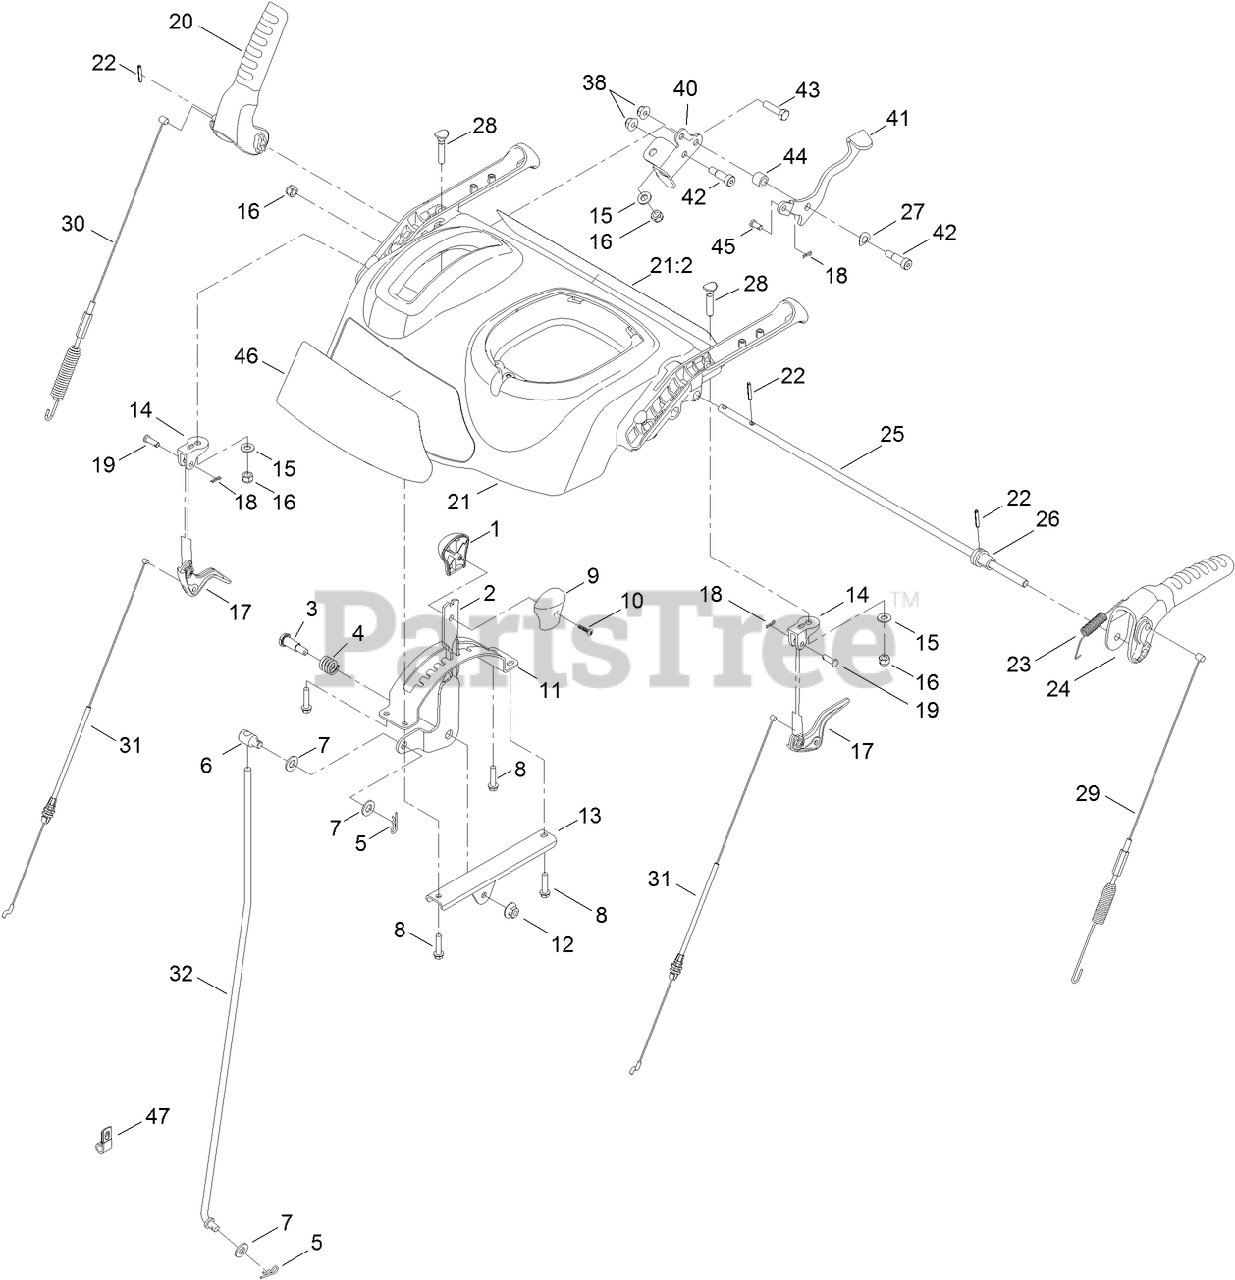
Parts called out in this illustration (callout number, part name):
1	KNOB-SHIFT, RH
2	SELECTOR-SPEED
3	SCREW-SHOULDER
4	SPRING-COMPRESSION
5	PIN-COTTER
6	TRUNNION-ROD
7	WASHER-FLAT
8	SCREW-PLASTITE
9	KNOB-SHIFT, LH
10	SCREW-PPH
11	GUIDE-SELECTOR, SPEED
12	NUT-HF
13	MOUNT-SELECTOR, SPEED
14	MOUNT-CLUTCH, LEVER
15	WASHER-FLAT
16	NUT-LOCK, NI
17	LEVER-CLUTCH
18	PIN-HAIR
19	PIN-CLEVIS
20	LEVER-AUGER
21	CONTROL PANEL ASM
21:2	DECAL-CONTROL, PANEL
22	PIN-SPRING
23	SPRING-TENSION
24	LEVER-TRACTION
25	ROD-LOCKOUT
26	CAM-LOCKOUT
27	WASHER-SPRING
28	SCREW-HANDLE
29	CABLE-TRACTION
30	CABLE-AUGER
31	CABLE-CLUTCH
32	ROD-SHIFT
38	NUT-HF, NI
40	BRACKET-LEVER, BROOM ANGLE
41	LEVER-THUMB, BROOM ANGLE
42	SCREW-SHOULDER, HSH
43	SCREW-HH
44	TUBE-SPACER
45	PIN-CLEVIS
46	DECAL-TORO, POWER BROOM
47	CLIP-LOOM
